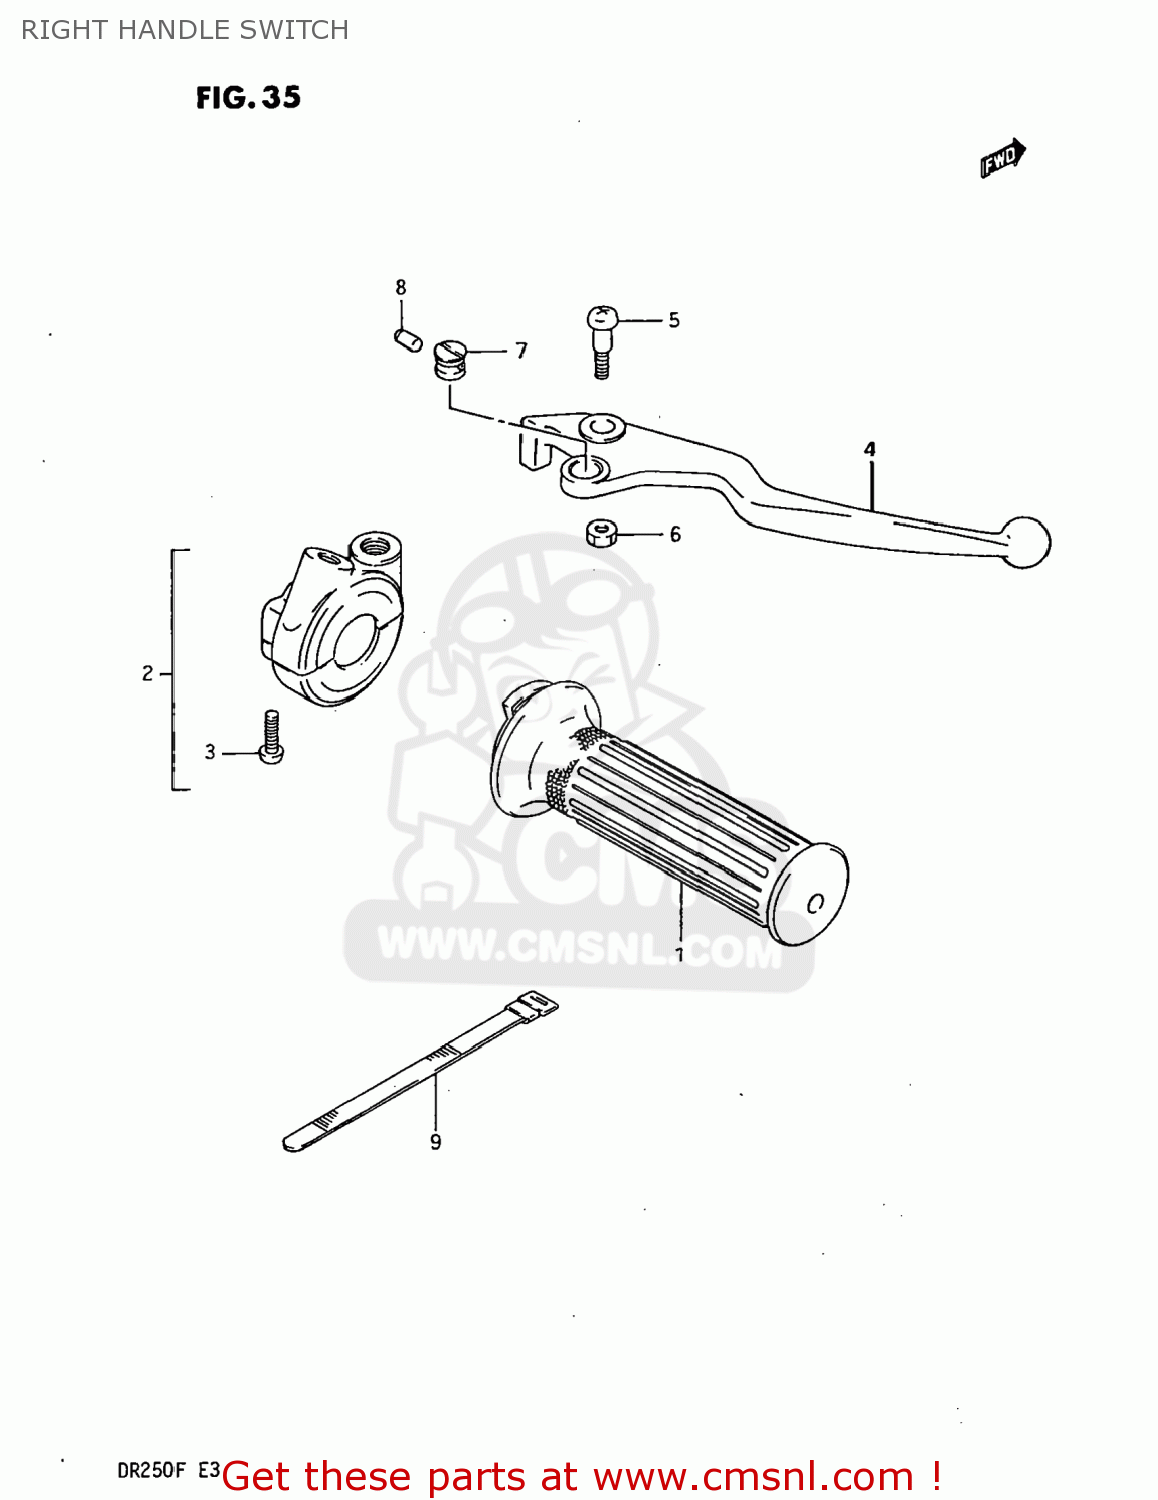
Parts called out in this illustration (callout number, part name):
1	GRIP,THROTTLE
2	CASE ASSY,THROTTLE
3	SCREW 5X20
4	LEVER,BRAKE
5	SCREW
6	NUT 6MM
7	ADJUSTER
8	ROD,PUSH
9	CLAMP(L:120)
